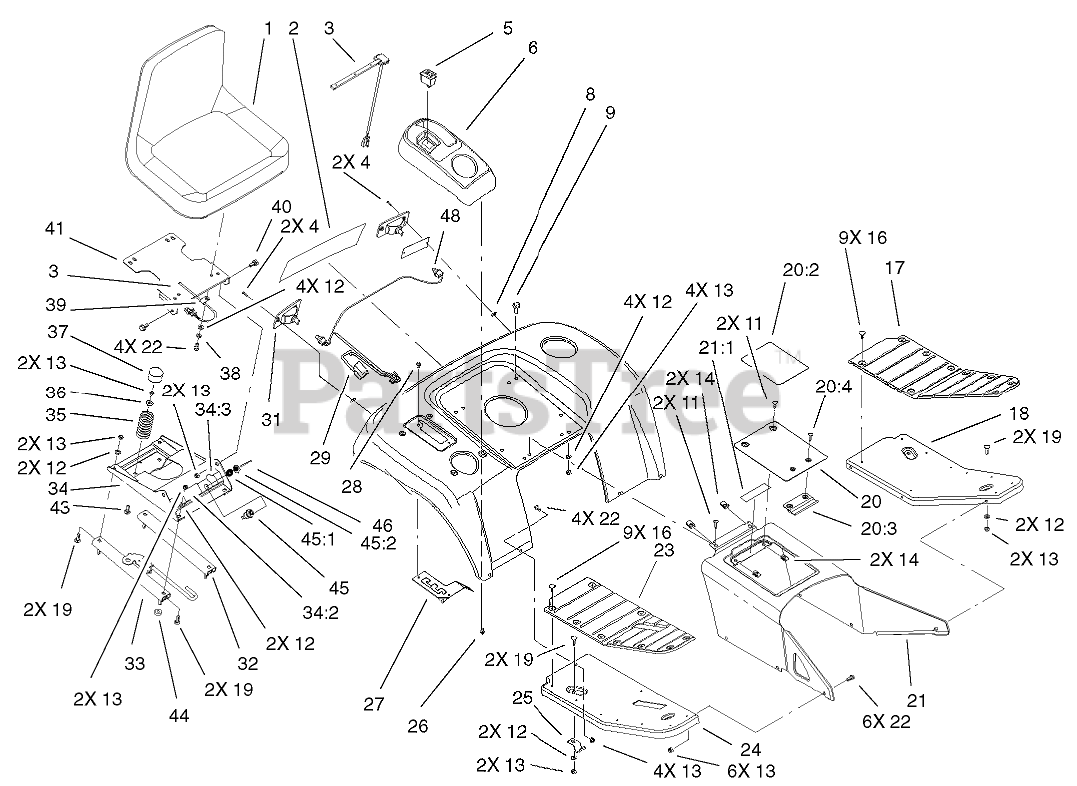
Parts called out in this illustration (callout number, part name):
1	SEAT
2	DECAL - FENDER
3	SWITCH-SEAT
4	SCREW-PPH
5	SWITCH-CRUISE
6	Pod-Control (only on: 73547)
6	Pod-Control Int-l (only on: 73580)
8	NUT-SPEED
9	SCREW-HHF
11	SCREW-HH
12	WASHER-PLAIN
13	NUT-LOCK, NI
16	FASTENER-PANEL
17	PAD-FOOTREST, LH
18	FOOTREST-LH
19	SCREW-CARR
20	Tunnel Cover ASM (only on: 73580)
20	Cover/Decal ASM (only on: 73547)
20:2	Decal-Danger (only on: 73580)
20:2	Decal-Danger (only on: 73547)
20:3	RETAINER-COVER
20:4	SCREW-PPH
21	Tunnel ASM (only on: 73580)
21	Tunnel ASM (only on: 73547)
21:1	Decal-Warning (only on: 73580)
21:1	Decal-Danger (only on: 73547)
22	SCREW-HH
23	PAD-FOOTREST, RH
24	FOOTREST-RH
25	BRACKET-FOOTREST
26	SCREW-HHFTF
27	GATE-HI / LO SHIFT
28	SCREW-HWH
29	HARNESS-REAR
31	LAMP-TAILLIGHT
32	SLIDE-SLAVE, SEAT
33	SLIDE-LATCH, SEAT
34	Seat Base ASM (only on: 73547)
34	Seat Base ASM, Intl Decal (only on: 73580)
34:2	Decal-Danger (only on: 73580)
34:2	Decal-Danger (only on: 73547)
34:3	Decal-Switch (only on: 73580)
34:3	Decal (only on: 73547)
35	SPRING-COMPRESSION
36	BUSHING
37	CAP-SPRING, SEAT
38	WASHER-LOCK
39	CLAMP-R
40	BOLT-SHOULDER
41	MOUNT-SEAT
43	SCREW-CARR
44	WASHER-FLAT
45	STARTER SWITCH ASM
45:1	WASHER-TOOTH, INTERNAL
45:2	NUT-HH
46	KEY-IGNITION
48	LIGHT BULB
